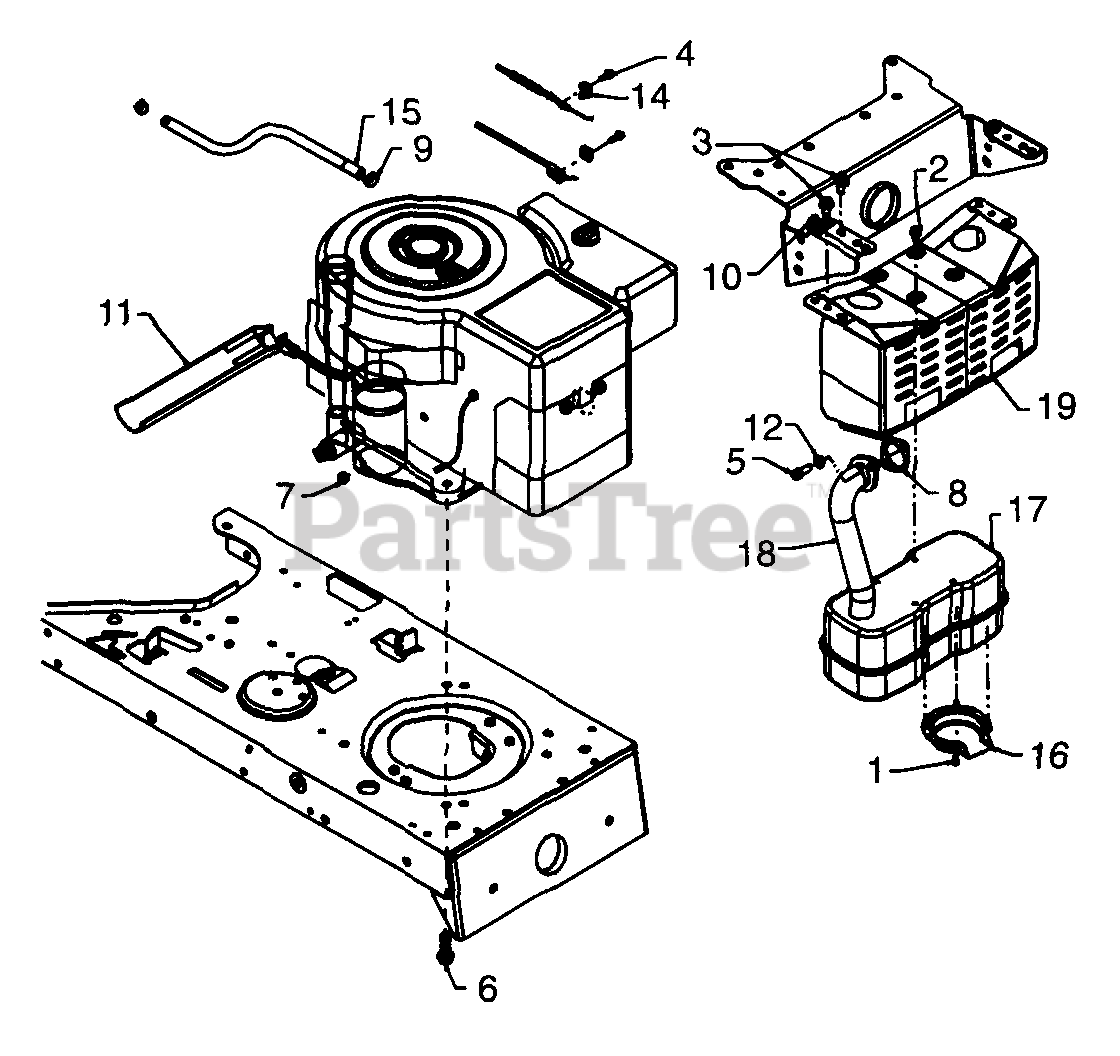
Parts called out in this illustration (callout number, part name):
1	Hex Tap Scr. #8-32 x .38" Lg,
2	Hex TT-Tap Scr. 1/4-20 x .5" Lg.
3	Hex TT-Tap Scr. 5/16-18 x .62"
4	Hex Wash. Scr. #10-32 x .62"
5	Socket Head Scr. 5/16-18 x .62"
6	Hex TT-Tap Scr. 3/8-16 x 1.25"
7	Hex Sems Scr. 1/4-20 Thd.
8	Gasket
9	Hose Clamp
10	Clamp
11	Oil Drain Sleeve
12	Lock Washer 5/16" I.D.
14	Casing Clamp
15	Fuel Line 12" Lg.
16	Muffler Deflector
17	Muffler
18	Exhaust Pipe
